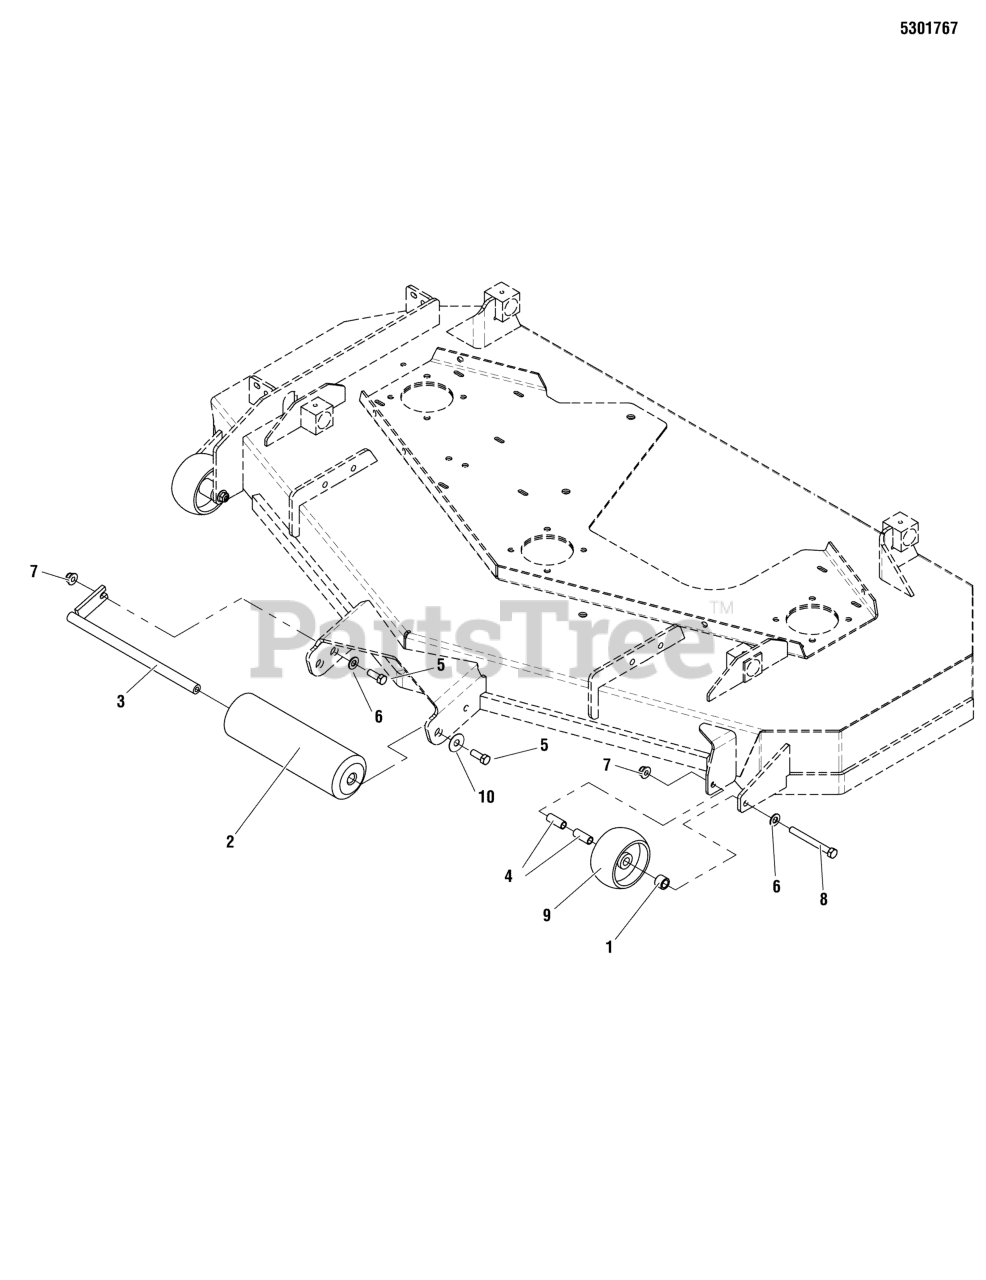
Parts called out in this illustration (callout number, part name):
1	SPACER, .51 X .75 X .56
2	ROLLER, DECK
4	SPACER, .38 X .50 X 1.25, CZ
5	BOLT, 3/8-16 X 1" GD5 CZ
6	WASHER, 3/8 SAE
7	NUT, 3/8-16 HEX NYLOCK FLANGE
8	BOLT, 3/8-16 X 3-1/2" GD5 CZ
9	WHEEL- 2.00 WIDE 3.88 DIA 0.531ID POLY
10	WASHER, .390 X 1.50 X .109, YZ
